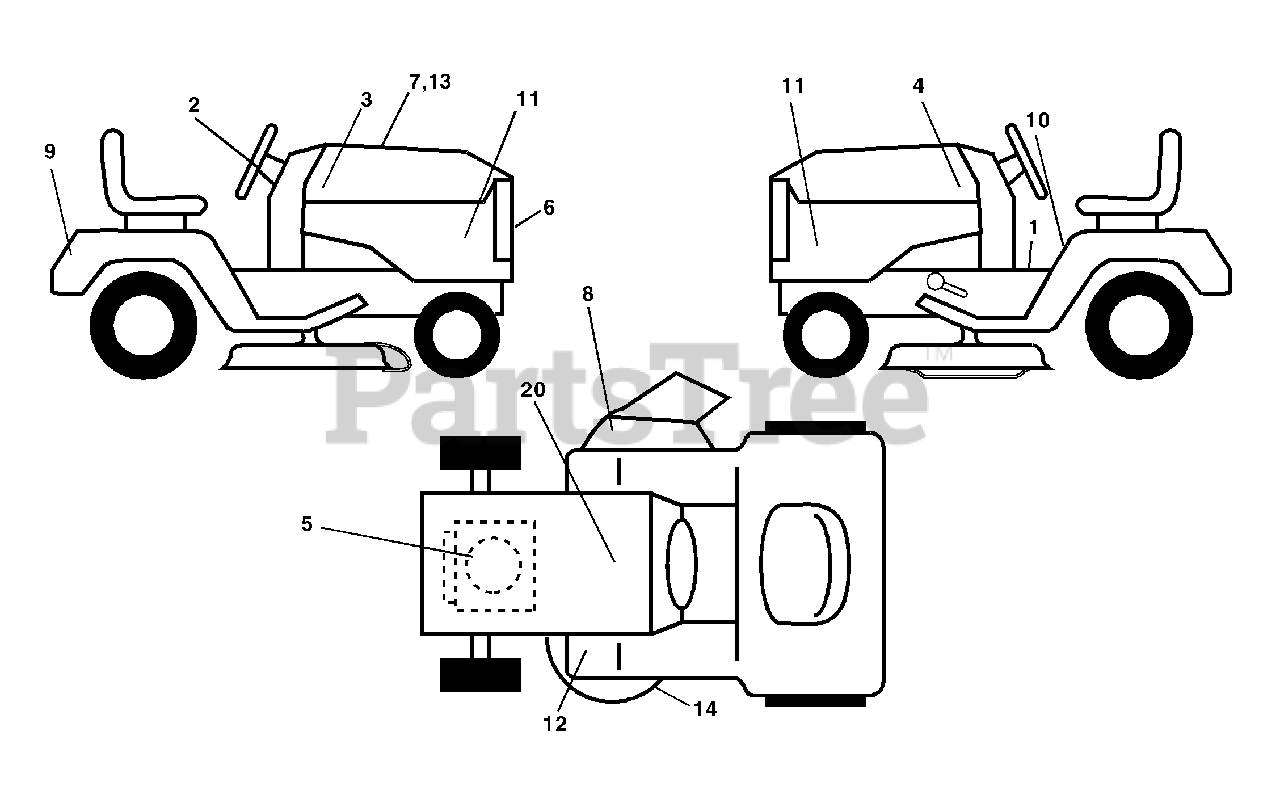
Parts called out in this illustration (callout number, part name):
1	Decal Oper Inst Hyd E/F
2	Decal Strg Wheel Logo
3	Decal Hood RH
4	Decal Hood LH
5	Decal Engine
6	Decal Grille Husq
7	Decal Repl. Parts
8	Decal Warning
9	Decal Fender Husq
10	Decal Fender Danger E/F
11	Decal Hood Sides
12	Decal Clutch/Brake
13	Decal Cust. Responsibilities
14	Decal V-Belt Schematic
20	Decal Bat Dan/Psn
